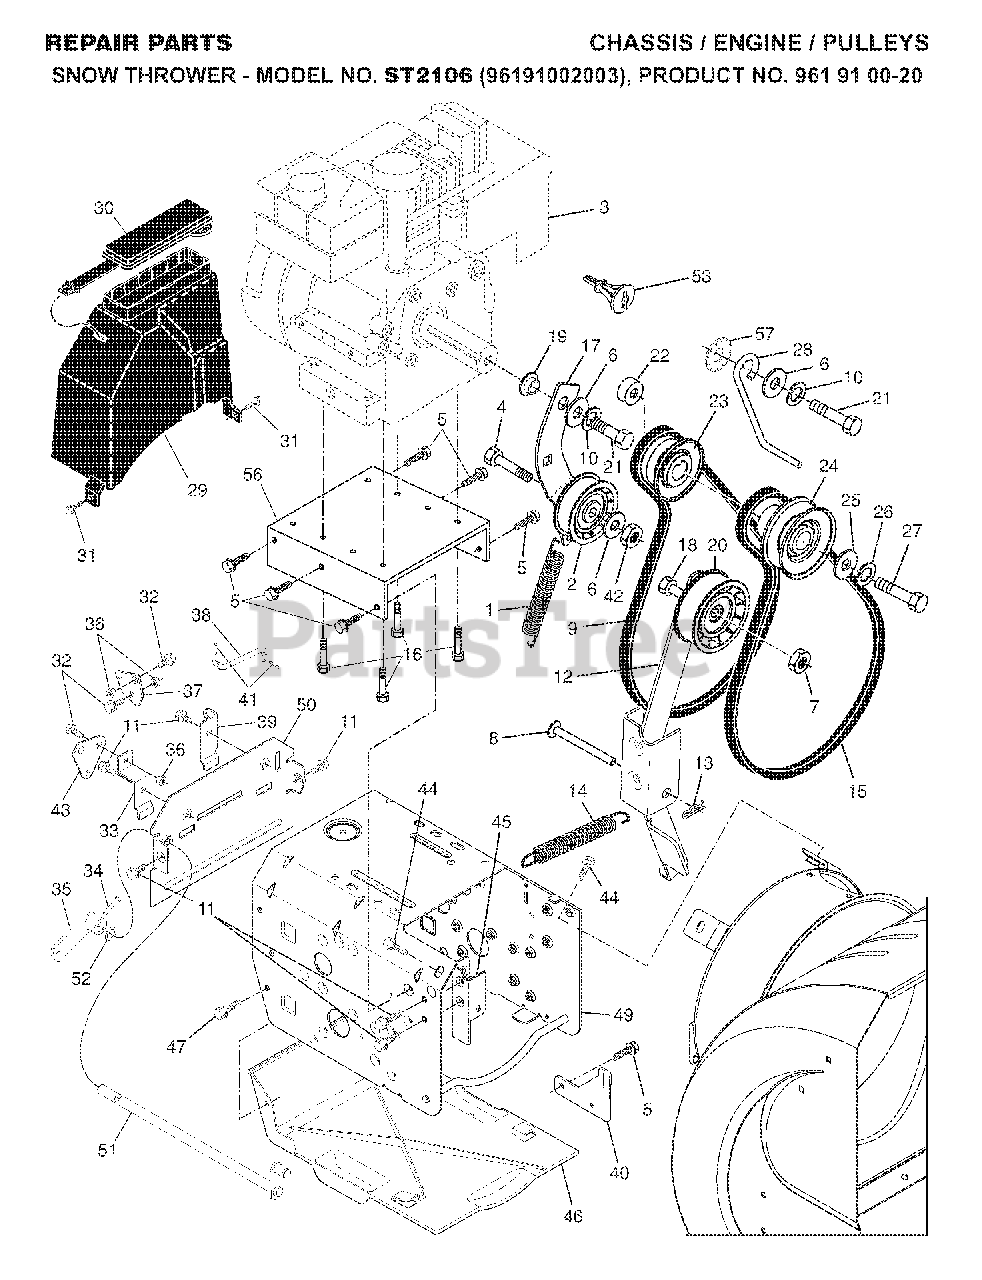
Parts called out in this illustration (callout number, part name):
1	RP SPRING, TRACTION IDLER
2	PULLEY.W/SPACER.2.25
4	BOLT.5/16-18X1-1/4 FULL.THREAD
5	SELF-TAPPING SCREW 5/16-18X3/4
6	STEEL WASHER
7	LOCKNUT 5/16-18
8	PIN, IDLER PIVOT
10	LOCKWASHER
12	ARM PAD ASSY
13	RETAINER CLIP PM
14	SPRING, BRAKE
15	BELT.V.IMPELLER
16	BOLT 3/8-16X1-1/8
17	IDLER ARM
18	HEX BOLT
19	BUSHING, IDLER PIVOT
20	PULLEY.W/SPACER.2.75
22	SPACER.ENGINE.PULLEY
23	PULLEY, ENGINE TRACTION DRIVE
24	PULLEY, ENGINE IMPELLER DRIVE
25	WASHER, FLAT 3/8
26	LOCKWASHER
27	SCREW, HEX HD 3/8-24 X 1-3/8
28	GUIDE BELT
29	COVER.ASM.BELT/STORAGE
30	COVER.STORAGE.SNOW
31	SCREW
32	BOLT.SHOULDER.3/X.25
33	BRACKET.SHIFTER.PLATE.BZP
34	CLEVIS PIN
35	ARM, AUGER CONTROL
36	NUT.HEX.FLANGE.1/4
37	PLATE.CLUTCH.BZP
38	LINK, SPEED CONTROL
39	BRACKET.CLUTCH.PLATE.BZP
41	RETAINER CLIP
42	PIN, PIVOT BRACKET
43	PLATE.SHIFTER.BZP
44	SCREW 3/8-16X1
45	BRACKET, IDLER PIVOT
46	PAN.BOTTOM.PLASTIC
47	SCREW, HEX HEAD, TAPPING
51	SHAFT, AUGER CONTROL
52	THRUST WASHER
53	KEY.PUSH/PULL.B&S.
55	RETAINING RING LT
57	WASHER EXT TOOTH LOCK 5/16
